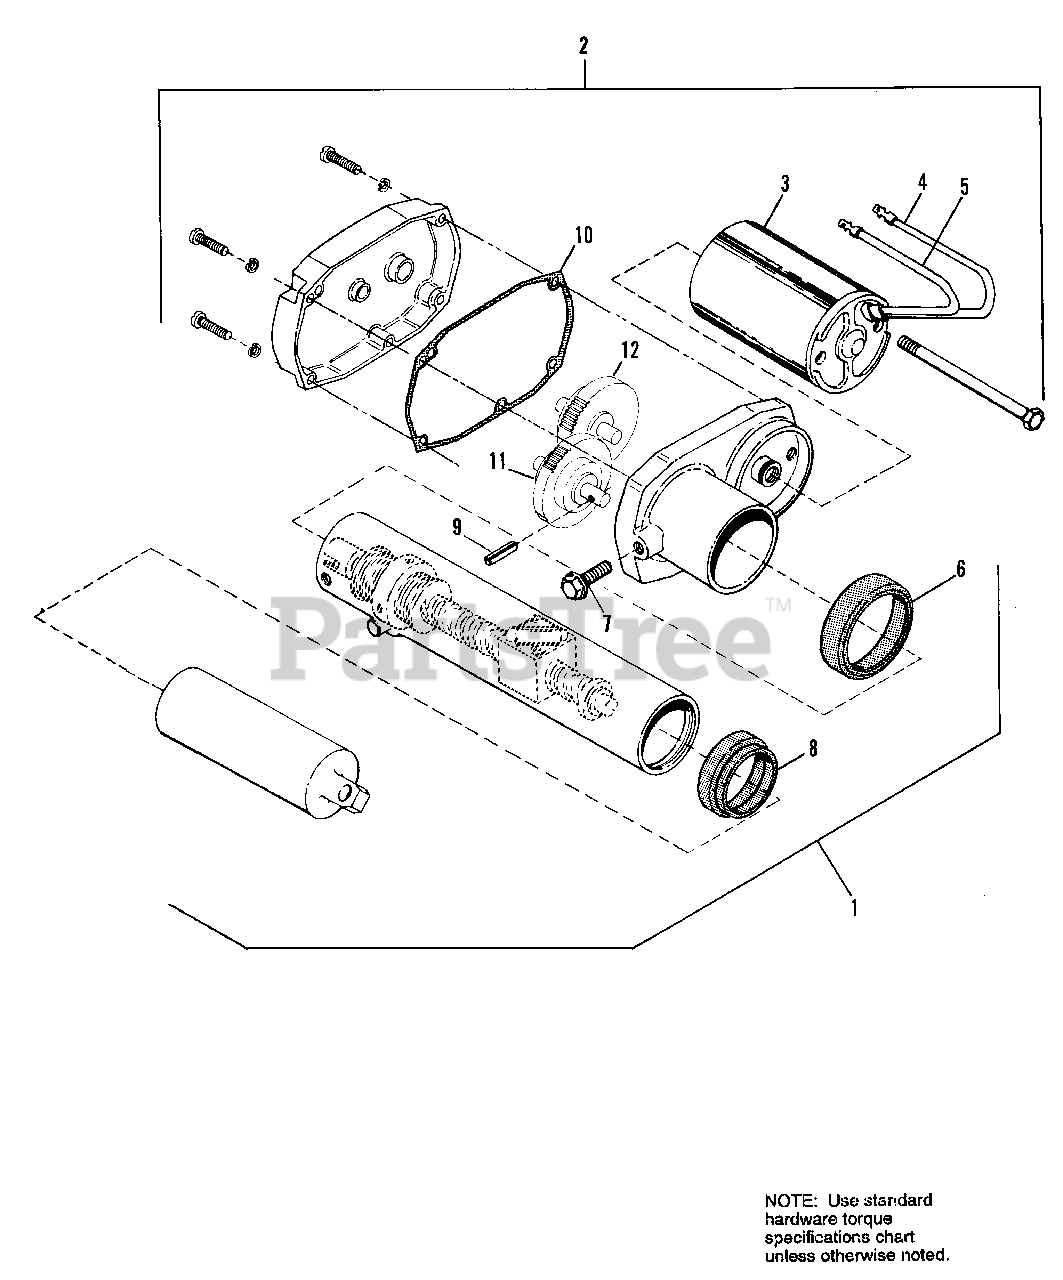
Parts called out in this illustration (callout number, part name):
1	BALL SCREW ASSY.
2	MOTOR & GEARBOX ASSY., 12 VDC, 17:1 Ratio
3	MOTOR KIT, 12 VDC
4	BRUSH & LEAD (Red)
5	BRUSH & LEAD (Black)
6	SEAL, Outer Tube (Top)
7	CAPSCREW, Taptite
8	SEAL, Inner Tube (Top)
10	GASKET, Housing
11	OUTPUT GEAR & SLIP CLUTCH ASSY.
12	GEAR ASSY., 2nd & 3rd
